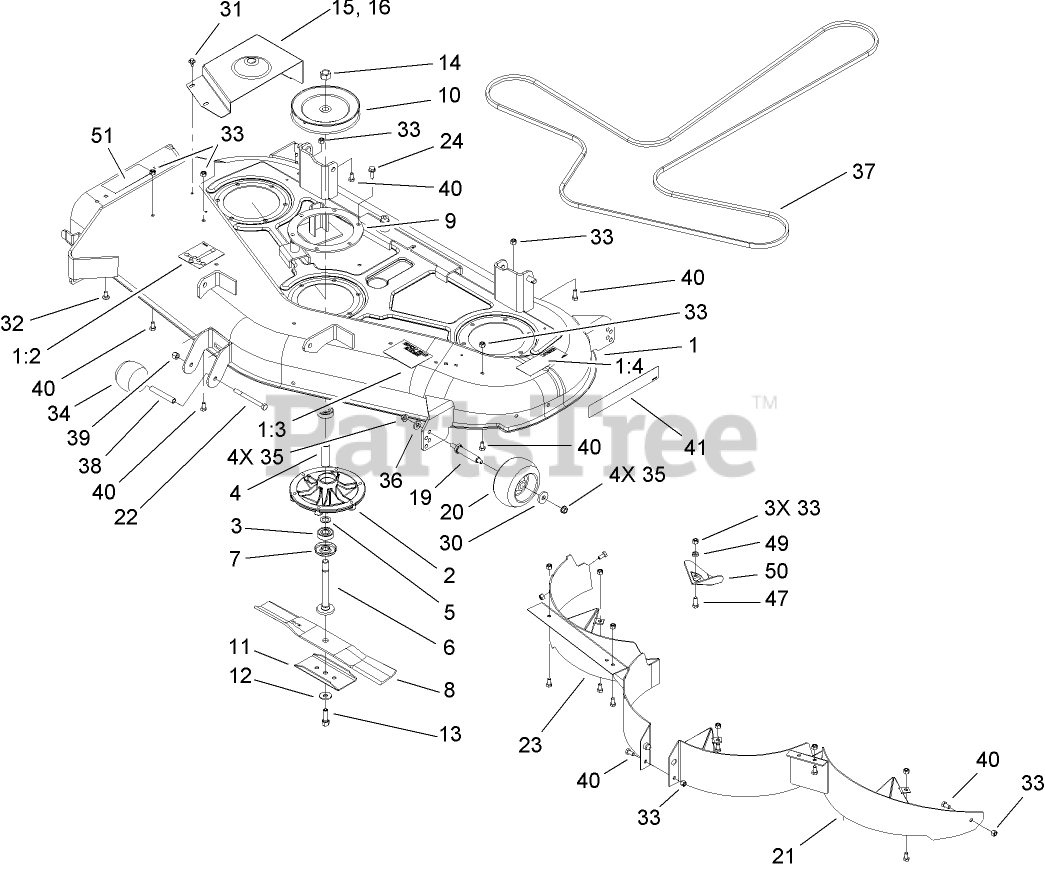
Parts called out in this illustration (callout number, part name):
1:2	DECAL-ROUTING, BELT
1:3	DECAL-ANTI SCALP
1:4	DECAL-DANGER
2	HOUSING-SPINDLE
4	SPACER
5	SPACER
6	SHAFT-SPINDLE
7	SHIELD-BEARING
8	BLADE-RECYCLER
9	RING-SUPPORT, DECK
10	PULLEY AND HUB ASM
11	STIFFENER-BLADE
12	WASHER-BELLEVILLE
13	SCREW-HH
14	NUT-HEX
15	COVER-BELT, LH
16	COVER-BELT, RH
21	LEFT BAFFLE ASM
22	SCREW-HH
23	RIGHT BAFFLE ASM
24	SCREW-TAPTITE
30	WASHER
31	SCREW-HHFTF
32	SCREW-CARR
33	NUT-LOCK, NI
34	ROLLER
35	NUT-HHF, WHIZ
36	WASHER-BELLEVILLE
37	BELT-V
38	TUBE-SPACER, WHEEL
39	NUT-LOCK, NI
40	SCREW-HH
41	DECAL-DECK
47	SCREW-HH
49	SPACER
50	PLATE-KICKER
51	DECAL-DANGER,RIDER,(CE)
